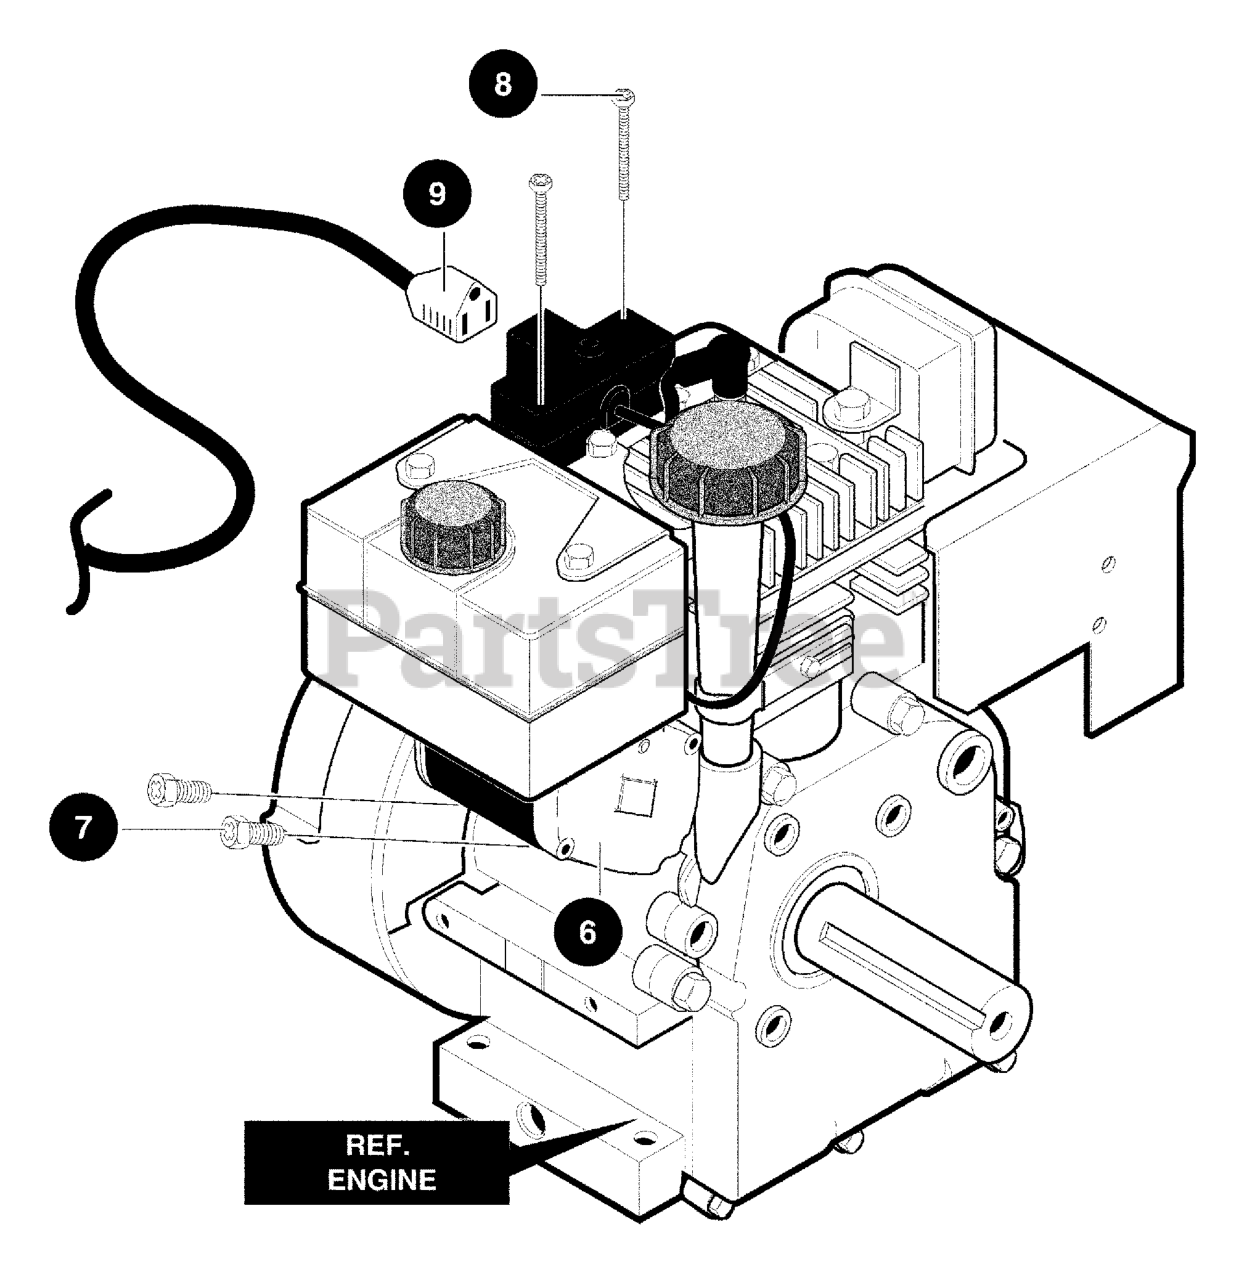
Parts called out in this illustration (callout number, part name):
6	MOTOR, STARTER
8	SCREW
9	CORD, STARTER
